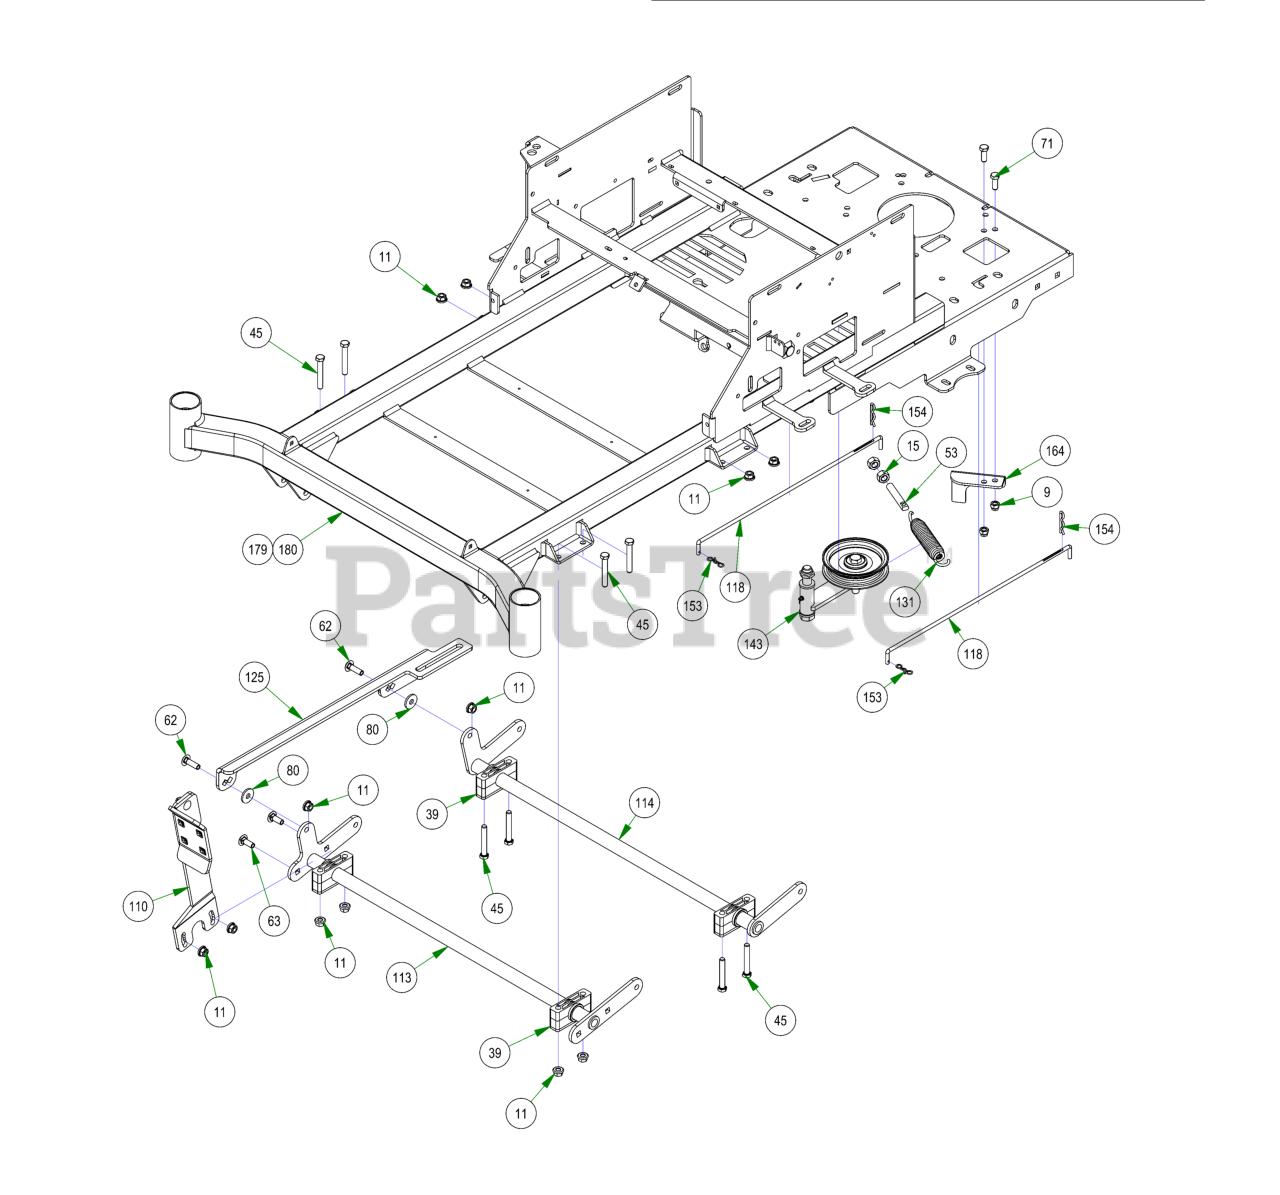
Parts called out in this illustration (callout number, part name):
9	3/8-16 NYLON INSERT LOCKNUT ZINC
11	3/8-16 NYLON INSERT FLANGE LOCKNUT (GR.F) ZINC
15	1/2-13 HEX NUT ZINC
39	Pillow Block Kit
45	3/8-16 X 2-1/2 HEX CAP SCREW (GR.5) ZINC
53	All Thread
62	3/8-16 X 1-1/4 CARRIAGE BOLT ZINC
63	3/8-16 X 1 CARRIAGE BOLT (GR.5) ZINC
71	3/8-16 X 1 GR 5 Hex Bolts Zinc
80	.390 ID X 1.12 OD X .125 THK FLAT WASHER NYLON
110	Foot Pedal Assembly
113	Actuator Bar Front- 2017 MZ/ZT
114	Actuator Bar Rear- 2017 MZ/ZT
118	Neutral Rod
125	2017 MZ/ZT Actuator Linkage
131	Deck Idler Spring
143	ZT Pump Idler
154	Neutral Rod Clip
164	2017 MZ Clutch Stop
179	2022 MZ/ZT 54"-60" Frame
180	2022 MZ/ZT 42"-48" Frame
